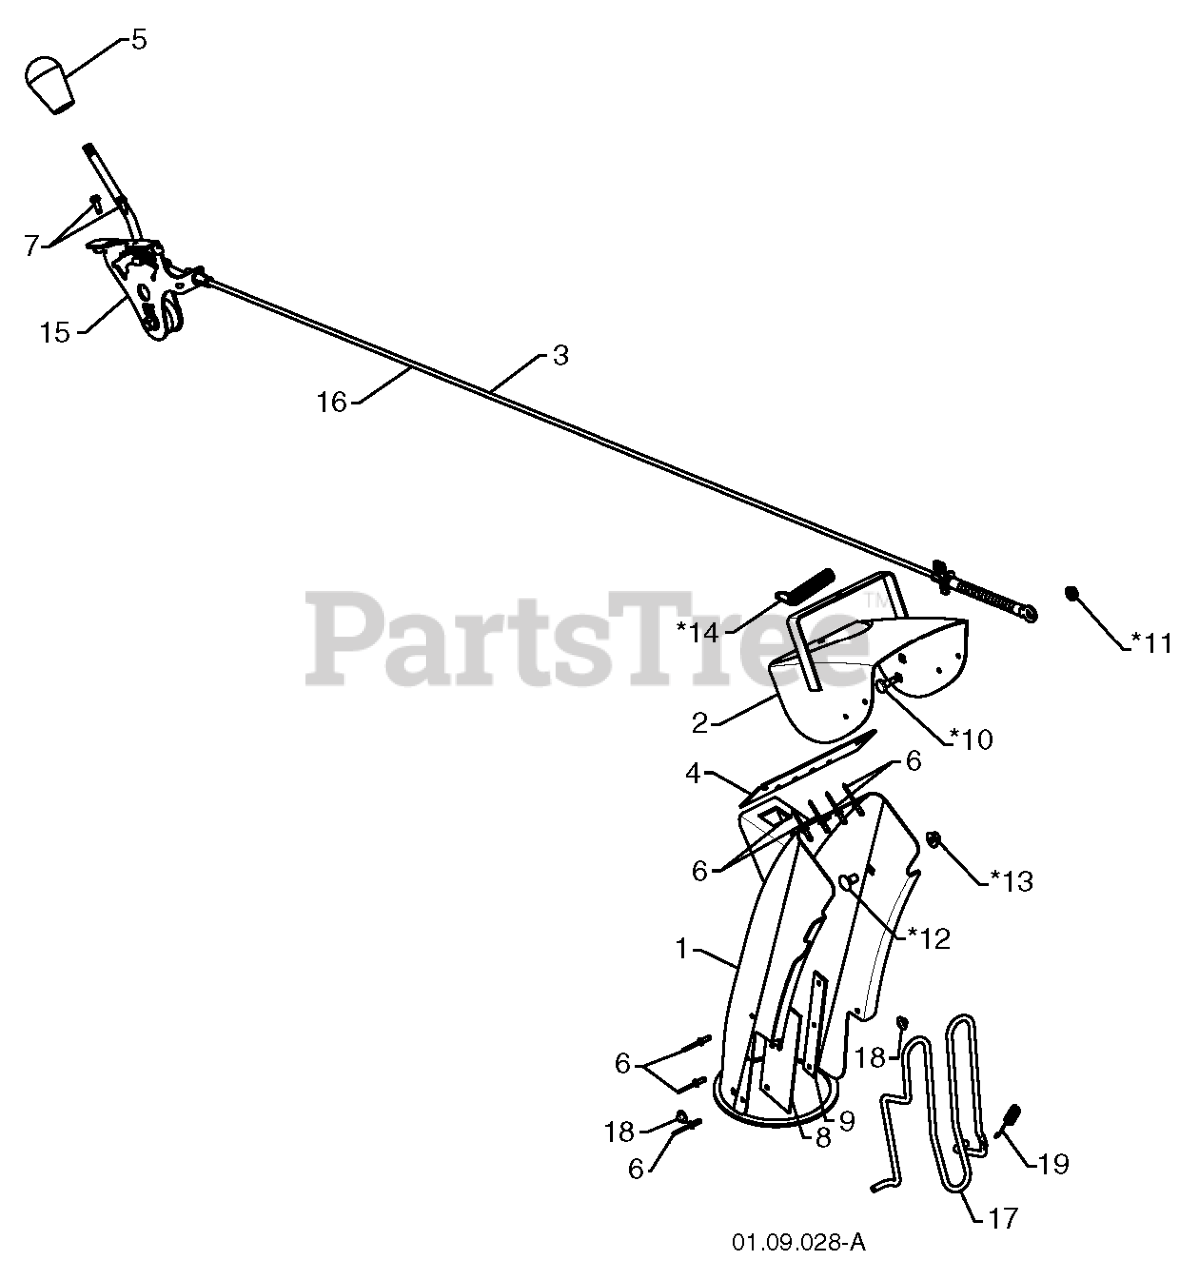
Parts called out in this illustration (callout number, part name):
1	CHUTE.WELDMENT.SNOW.RED
2	DEFLECTOR.WELDMENT.RED
3	RP.CONTROL.ASM.DEFLECTOR.SNOW
4	SEAL.DEFLECTOR
5	KNOB LEVER, BLACK
6	RIVET BLIND
7	SCREW #10-24 X 5/8
8	SHIELD.SNOW.CHUTE
9	STRAP.SHEILD.RETAINER
10	BOLT, SHOULDER
11	NUT.HEX.FLANGE.1/4
12	BOLT
13	NUT.LOCK.5/16-18
14	SPRING.DEFLECTOR.REM.CHUTE
15	RP CNTRL.HEAD.ASSEM.DEFLECTOR
16	RB SERVICE.CHUTE.DEF.CBL.BLK
17	ROD.GUARD.CHUTE (2 2)
18	NUT
19	SPRING.CHUTE.GUARD
